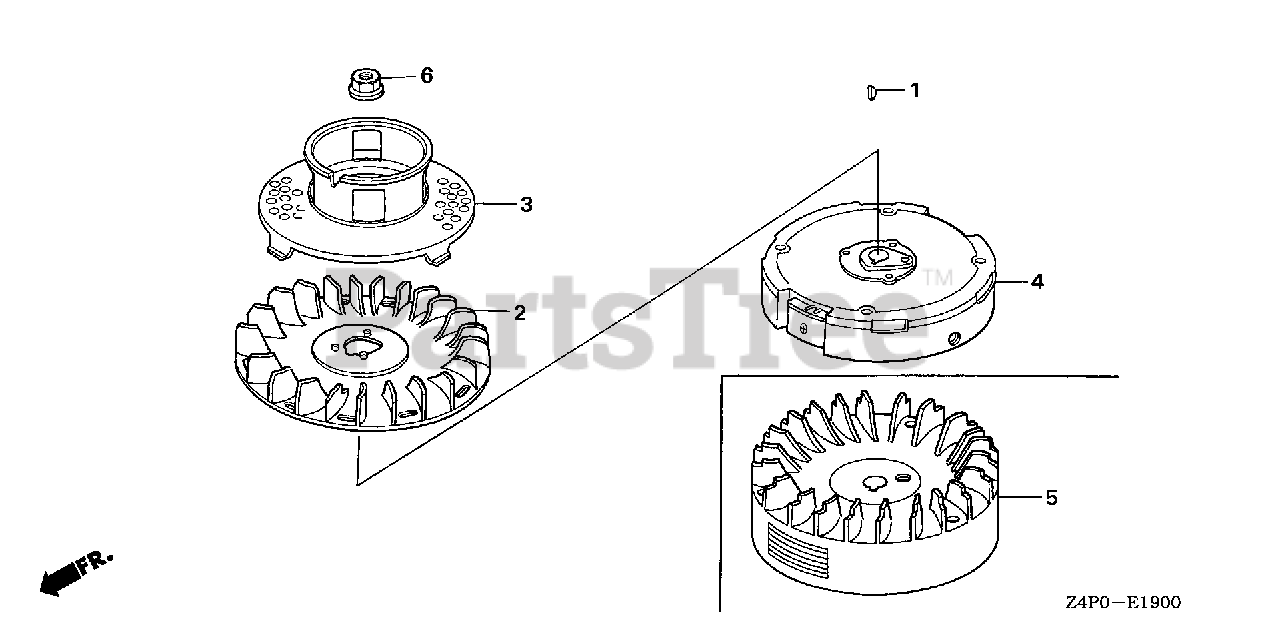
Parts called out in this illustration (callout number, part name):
1	KEY, SPECIAL WOODRUFF (25X18)
2	FAN, COOLING
3	PULLEY, STARTER
6	NUT, SPECIAL (14MM)
